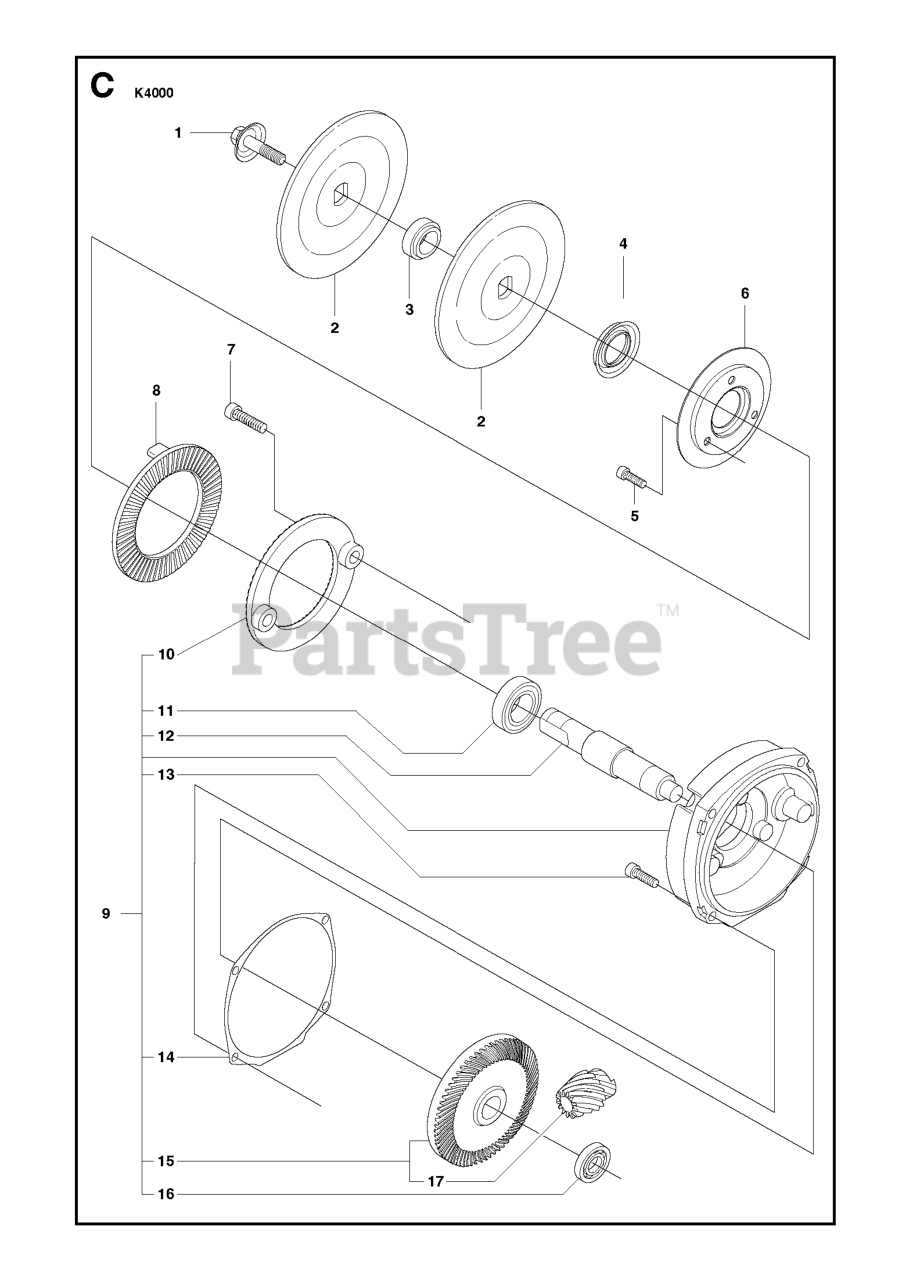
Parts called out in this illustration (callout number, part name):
2	WASHER
2	FLANGE
3	BUSHING
3	BUSHING ASSY BLADE WITH O-RING
5	SCREW ITXSCM
9	GEAR SET
11	BALL BEARING
13	SCREW ITSXCM
15	GEAR CPL.
16	BALL BEARING
